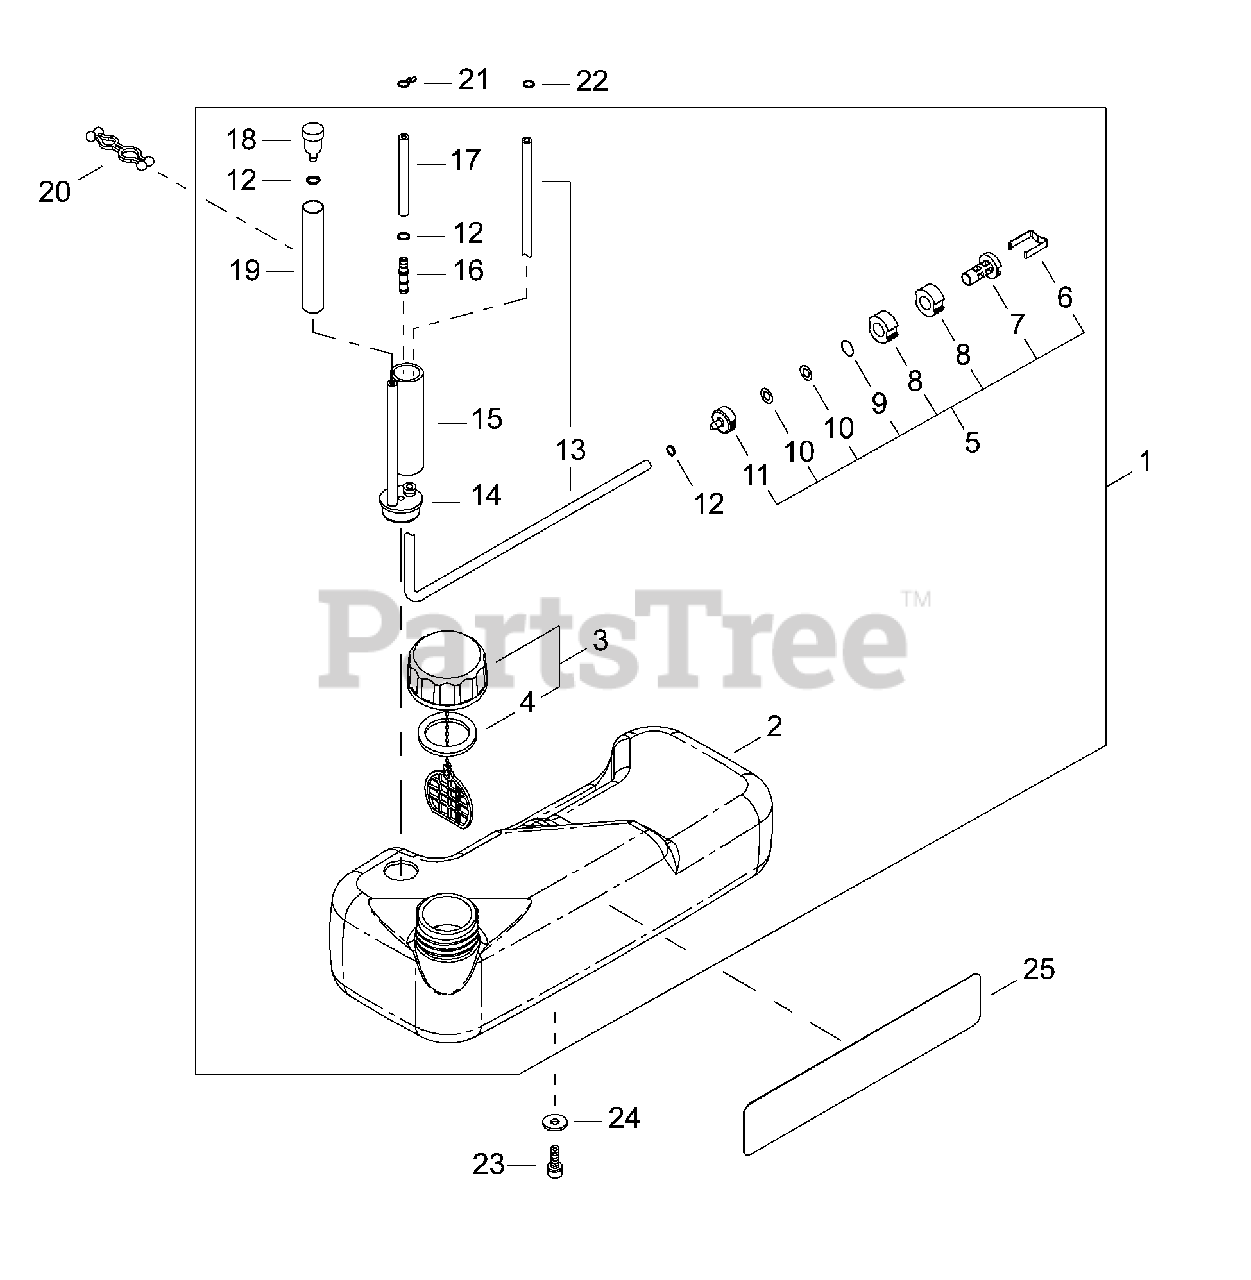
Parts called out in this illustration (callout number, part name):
1	TANK ASSY, FUEL
2	TANK, FUEL
3	CAP ASSY, FUEL
4	GASKET, FUEL CAP
5	FILTER, FUEL
6	CLIP, FILTER
7	BODY, FUEL FILTER
8	FILTER, FUEL
9	RING, RETAINING
10	SCREEN, FILTER
11	WEIGHT, FUEL LINE
12	CLIP Ø6
13	PIPE, FUEL
14	GROMMET, FUEL W/VENT PIPE
15	SLEEVE
16	CONNECTOR, PIPE
17	PIPE, FUEL RETURN
18	VENT ASSY
19	TUBE, INSULATOR
20	CLIP
21	CLIP, SPRING Ø5.2
22	CLIP Ø6
23	BOLT, ADHESIVE M5×14
24	WASHER Ø15ר5.2×1.6
25	LABEL, SHINDAIWA PROFESSIONAL
